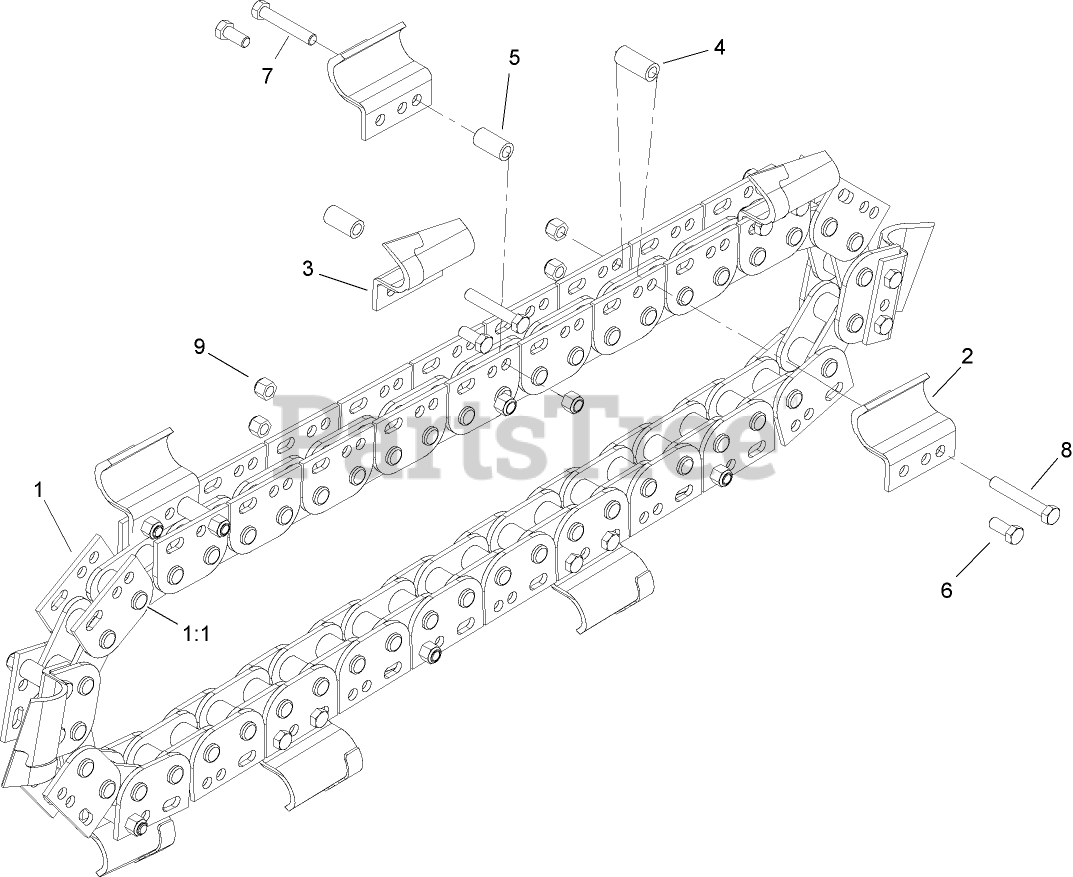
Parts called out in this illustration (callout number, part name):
1	CHAIN-BARE, 24 STATION
1:1	PIN-CONNECTING
2	TOOTH-SOIL, RH
3	TOOTH-SOIL, LH
4	SPACER-TUBE
5	SPACER-TUBE
6	SCREW-HH
7	SCREW-HH
8	SCREW-HH
9	NUT-LOCK
